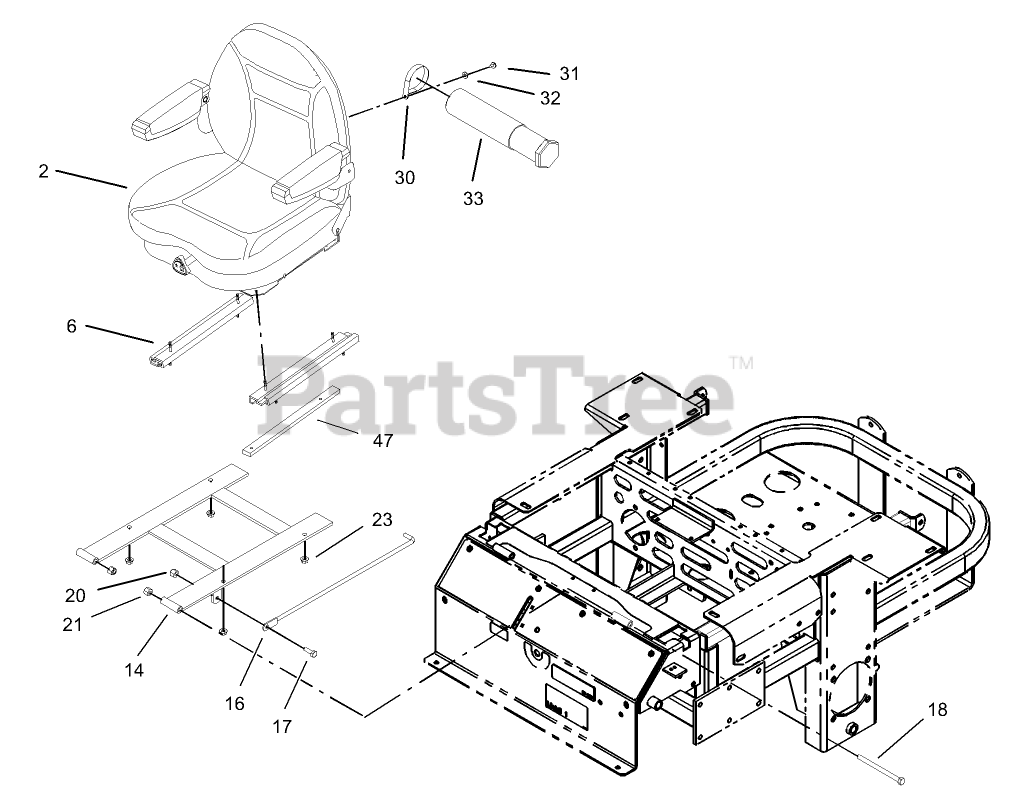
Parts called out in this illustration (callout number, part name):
2	Seat ASM (only on: 74236)
2	Seat Suspension Kit (only on: 74213)
6	Track-Seat (only on: 74213)
14	FRAME-SEAT
16	ROD-HOLDUP, SEAT
17	SCREW-HH
18	SCREW-HH
20	NUT-LOCK, NI
21	NUT-LOCK, NI
23	NUT-HF
30	CLAMP-R
31	Screw-HH (only on: 74213)
31	Screw (only on: 74236)
32	Washer-Flat (only on: 74236)
33	TUBE-MANUAL
47	STOP-SEAT
